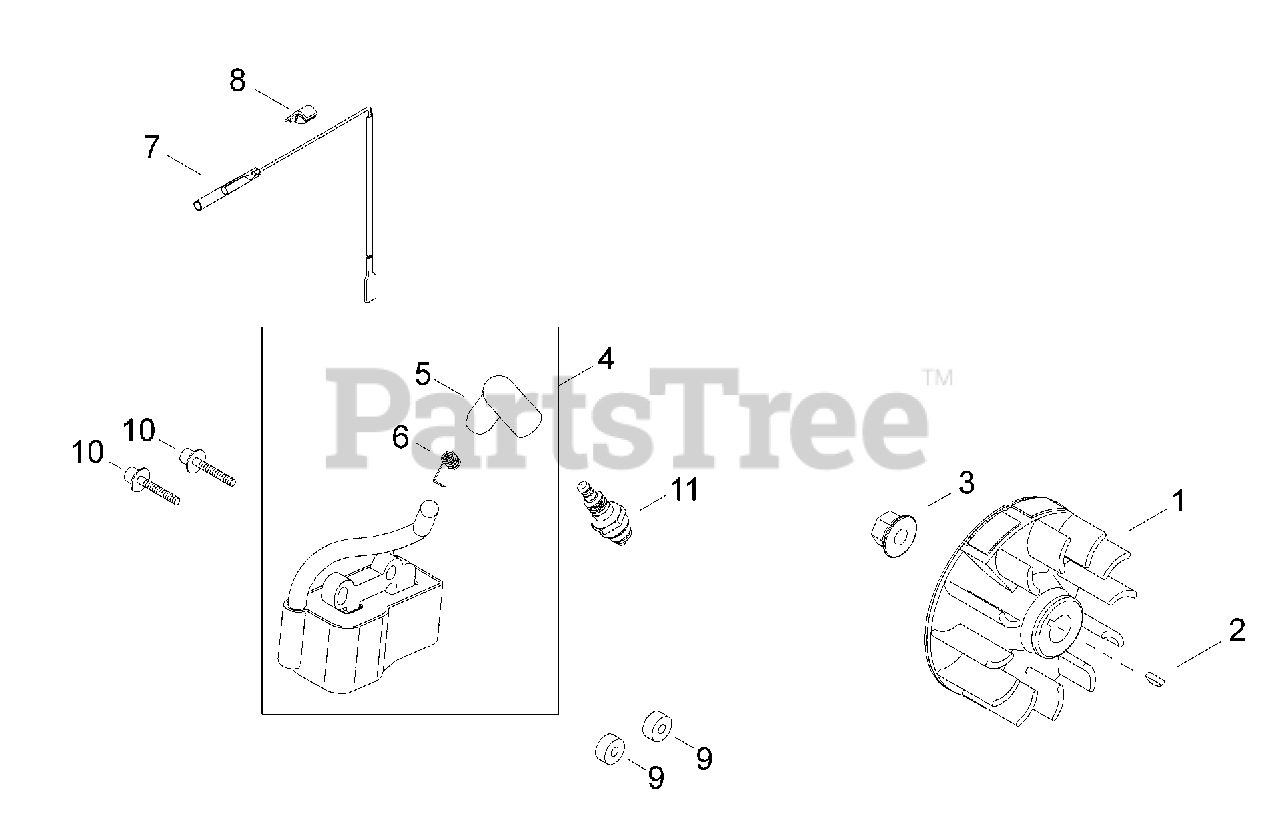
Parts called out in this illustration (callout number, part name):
1	FLYWHEEL
2	KEY - 3X10
3	NUT - 8
4	IGNITION COIL ASSY
5	CAP, SPARK PLUG
6	TERMINAL, SPARK PLUG CAP
7	LEAD - IGNITION
8	GROMMET
9	INSULATOR
10	SCREW - 4X26
11	SPARK PLUG -- CMR-5H
